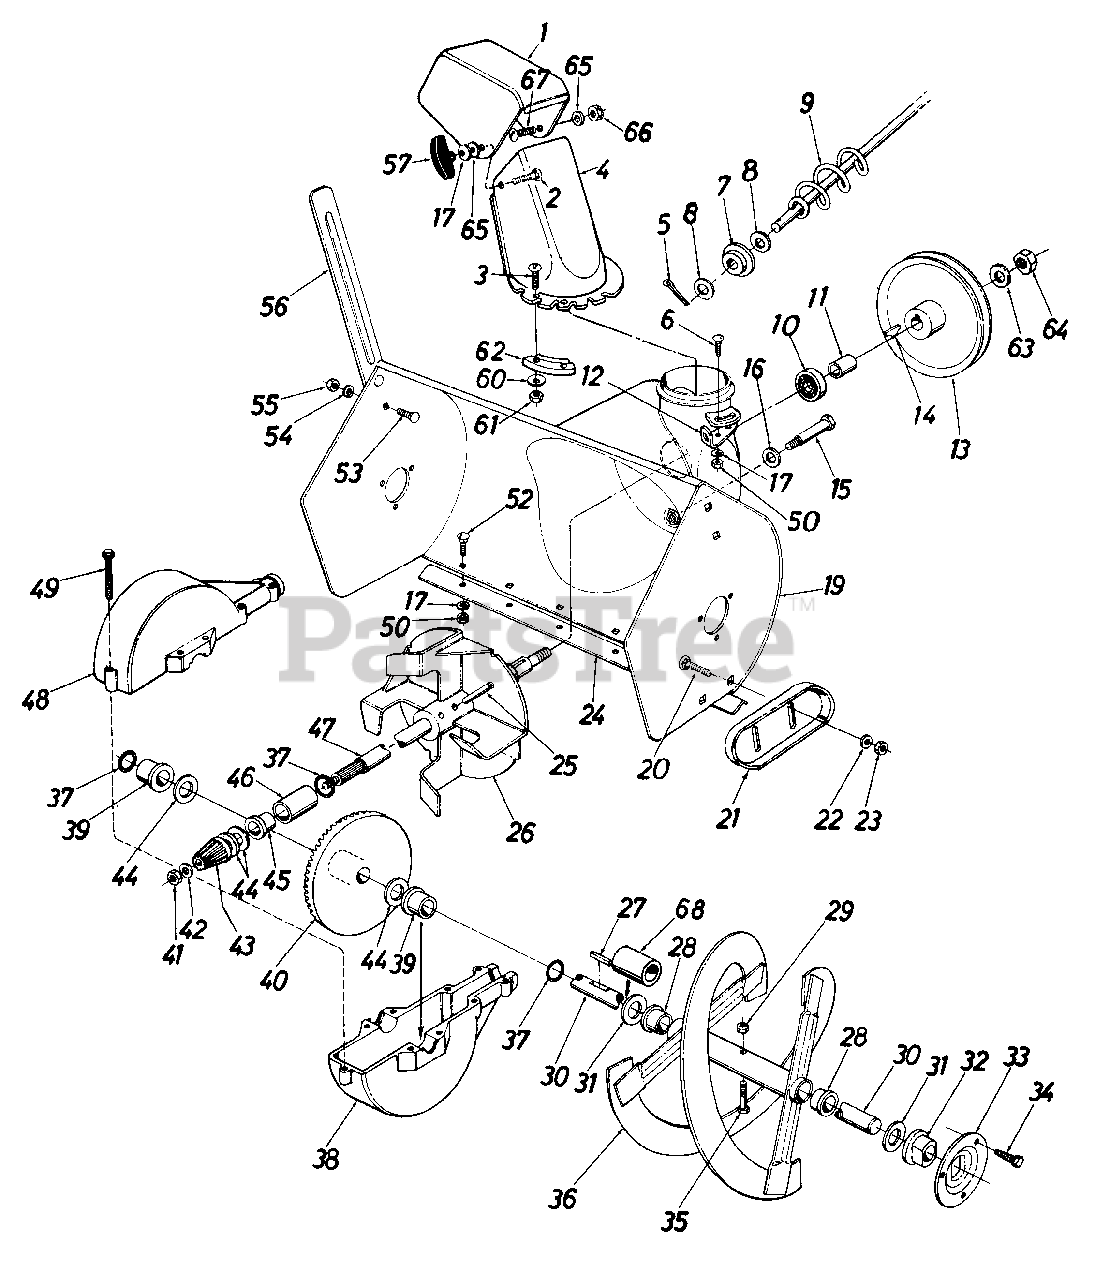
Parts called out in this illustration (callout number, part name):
1	Upper Chute
2	Carriage Bolt 5/16-18 x 1.0"
3	Truss Mach. Scr. 1/4-20 x .75"
4	Lower Chute
5	Cotter Pin
6	Carriage Bolt 5/16-18 x .75"
7	Bushing
8	Fl-Wash. .385 I.D. x .62" O.D.
9	Chute Crank Ass'y.
10	Ball Brg. .62" I.D. x 1.38" O.D.
11	Spacer .63" I.D. x .88" O.D. x .900" Lg.
13	1/2" "V"-Pulley .625" I.D. x 7.50" O.D.
14	#61 Hi-Pro Key 3/16" x 518" Dia.
15	Shld. Bolt .50" Dia. x 2.11"
16	Bell-Wash. .40n I.D. x .88" O.D. x .06
17	Bell-Wash. .34" I.D. x .88" O.D.
20	Carriage Bolt 3/8-16 x .62"
21	Slide Shoe
22	Bell-Wash. 3/8" I.D.
23	Hex Jam Nut 3/8-16 Thd.
24	20" Shave Plate
26	11" Dia. Blower Fan Ass'y.
27	Sq. Key 3116" x 1.5" Lg.
28	Flange Brg. .75" I.D. x .88" O.D.
29	Hex Ins. L-Nut 5/16-18
30	Spiral Axle
31	Fl-Wash. .75n I.D. x 1.50" O.D. x .06
32	Flange Brg. w/Flats .755" I.D.
33	Bearing Housing
34	Hex Wash. Hd. Self-Tap Scr. 5/16-24 x .62" Lg.
35	Hex Bolt 5/16-18 x 1.50" Lg.
36	20" Spiral Ass'y.-L.H.
37	"O"-Ring-3/4" I.D.
38	Bevel Gear Housing-Lower Half
39	Plastic Flange Brg. .755" I.D.
40	Bevel Gear
41	Hex Cent. L-Nut 5/16-24 Thd.
42	Fl-Wash. .34" I.D. x .62" O.D. x .06
43	Pinion Gear
44	Fl-Wash. .75" I.D. x 1.25" O.D. x .06
45	Flange Brg. .755" I.D.
46	Sleeve Brg. .755" I.D.
47	Blower Axle
48	Bevel Gear Housing- Upper Half
49	Hex Wash. Hd. Self-Tap Scr. 1/4-20 x 1.00" Lg.
50	Hex Nut 5/16-18 Thd.*
52	Carriage Bolt 5/16-18 x .62" Lg.*
53	Carriage Bolt 5/16-18 x .62" Lg.*
54	L-Wash. 5/16" I.D.*
55	Hex Nut 5/16-18 Thd.*
56	Drift Cutter Bar
57	Knob
60	Fl-Wash. 1/4" I.D.
61	Hex L-Nut 1/4-20 Thd.*
62	Chute Flange Keeper
63	Fl-Wash. 54" I.D. x .94 O.D. x .06
64	Hex Jam Nut 5/8-18 Thd.
65	Fl-Wash. .344 I.D. x 1.125 O.D.
66	Hex L-Nut 5/16-18 Thd.
67	Truss Mach. Scr. 5/16-18 x 75" Lg. *
68	Spacer
